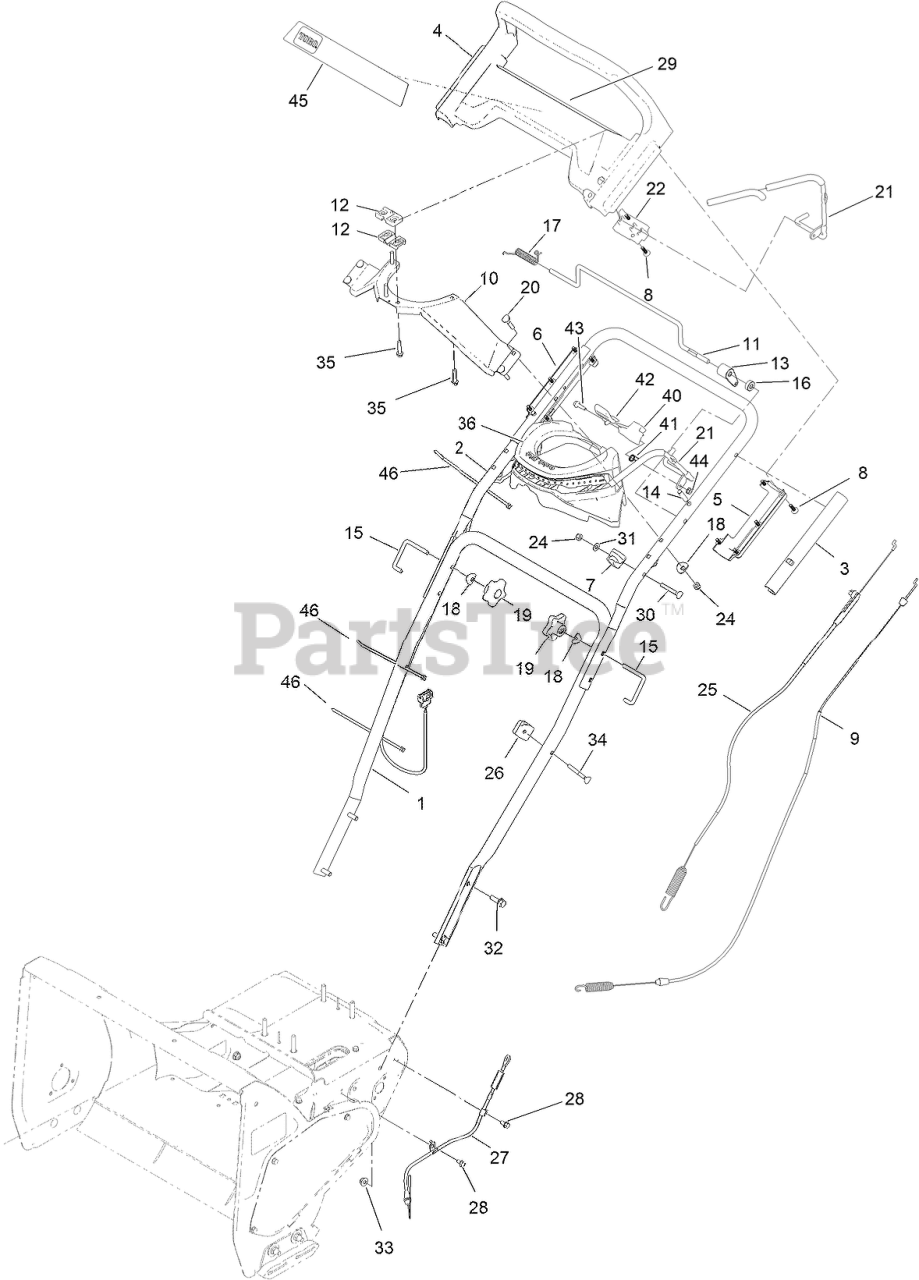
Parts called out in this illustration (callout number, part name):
1	HANDLE-LOWER
2	HANDLE-UPPER
3	SLEEVE HANDLE
4	HANDLE PP ASM W/ DECAL
5	HANDLE-BOTTOM, LH
6	HANDLE-BOTTOM, RH
7	CABLE-GUIDE
9	CABLE-TRANSMISSION
10	BRACKET-CHUTE, CONTROL
11	BAR-CONTROL, TRACTION
12	SUPPORT-ROD
13	LEVER-TRACTION
14	PIN-DOWEL
15	LOCK-HANDLE
16	SPACER
17	SPRING-TORSION
18	WASHER-CUP
19	KNOB-HANDLE
20	SCREW-HANDLE
21	ASM-BAIL
22	BAIL-MOUNT
24	NUT-HEX
25	CABLE-ROTOR, UPPER
26	ANCHOR-CABLE, UPPER
27	CABLE-ROTOR, LOWER
28	SCREW-HWH
29	DECAL-CONTROL, PANEL
30	BOLT-CARR
31	WASHER-FLAT
32	SCREW-HHF
33	NUT-HF
34	SCREW-HANDLE
35	SCREW-PLASTIC,HWH
36	HEADLIGHT-SNOWMASTER
41	SPRING-TORSION
43	SCREW-SHOULDER
44	NUT-HEX FLANGE
45	DECAL-DISPLAY
46	TIE-CABLE
